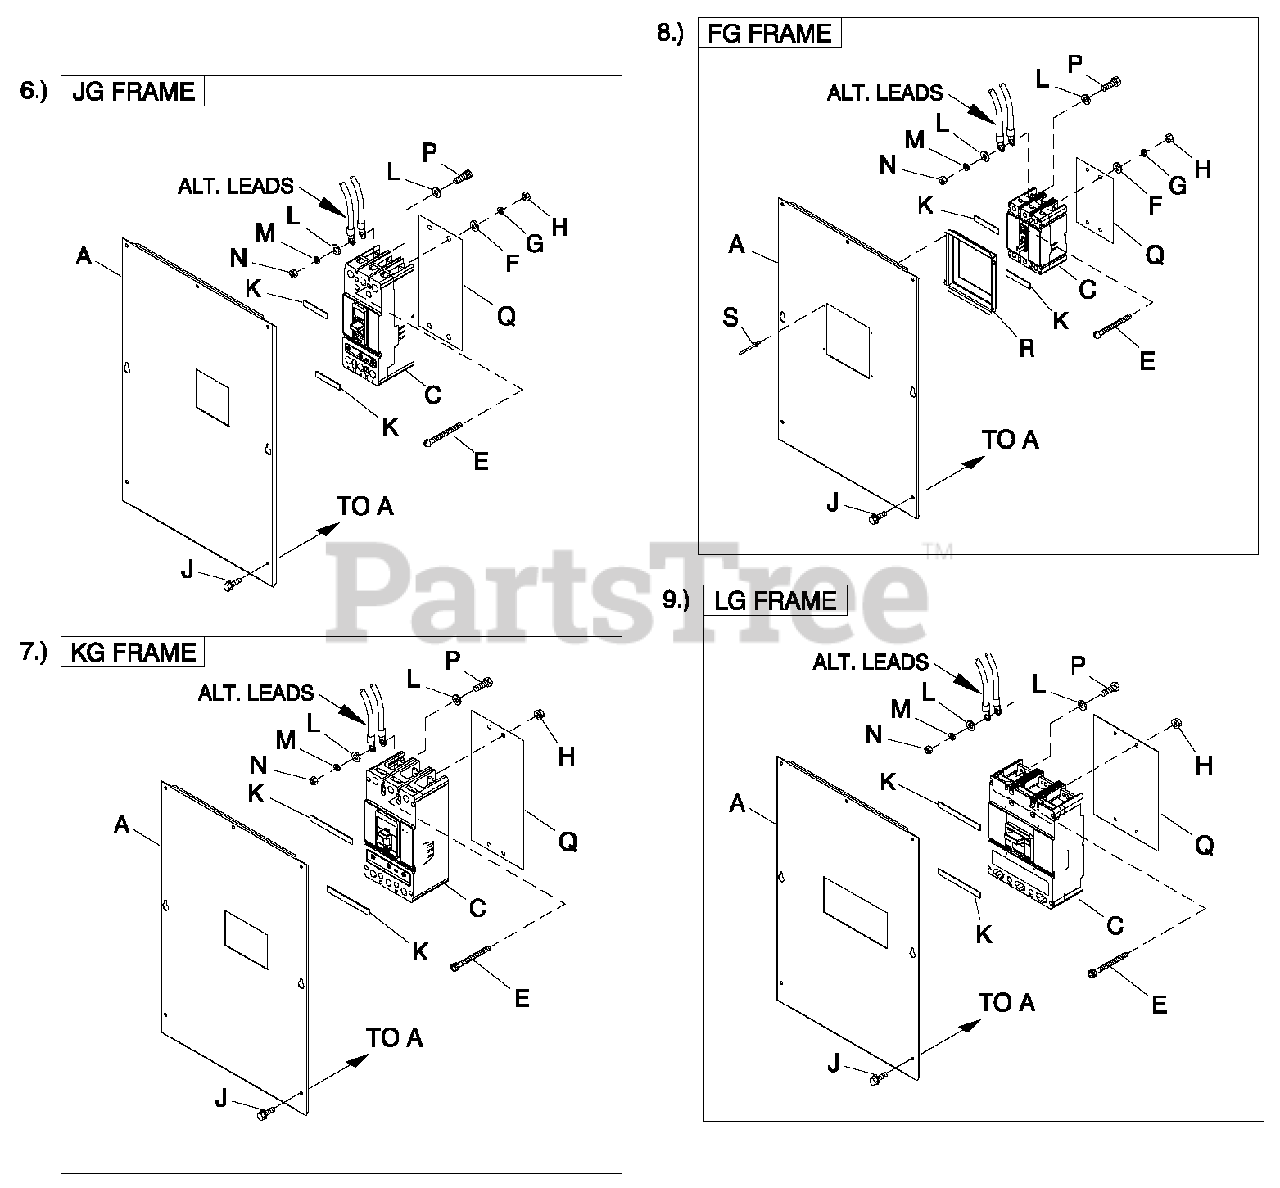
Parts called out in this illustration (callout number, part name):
A	COVER CB E JG FRAME C5
C	CB 0250 3P 600V E JG LL
E	SCREW RHM 1 /4-20X 3
F	W ASHER FLAT 1/4-M6 ZINC
G	W ASHER LOCK M6-1/4
H	NUT HEX 1/4-20 STEEL
J	SCREW THF M6-1 X 16 N W A Z/JS
K	TAPE ELEC 1/2 FOAM
L	W ASHER FLAT 5/16-M8 ZINC
M	W ASHER LOCK M8-5/16
N	NUT HEX M8-1.25 G8 CLEARZINC
P	SCREW HHC M8-1.25 X 25 C8.8
Q	INSULATOR CB E 3P JG
A	COVER CB E KG FRAME C5
C	CB 0350 3P 600V E KG LL
E	SCREW SHC M6-1.0 X 50 C8.8
H	NUT FLANGE M6-1.0 NYLOK
Q	INSULATOR CB E 3P KG
A	COVER CB G 225AF C5
C	CB 0150 3P 480V E FG LL
E	SCREW PPHM #8-32 X 1-3/4 ZINC
F	W ASHER FLAT #8 ZINC
G	W ASHER LOCK #8-M4
H	NUT HEX #8-32 STEEL
L	W ASHER FLAT #10 ZINC
M	W ASHER LOCK M5
N	NUT HEX M5-0.8 G8 CLEAR ZINC
P	SCREW HHC M 5-0.8X 20 G8.8
Q	INSULATOR CB 3P E TYPE CC/FG
R	COVER CB DISH 3P E FD
S	RIVET POP .125 X .275 SS
A	COVER CB E LG FRAME C5
C	CB 0450A 3P 600V E LG LL
Q	INSULATOR CB E 3P LG
